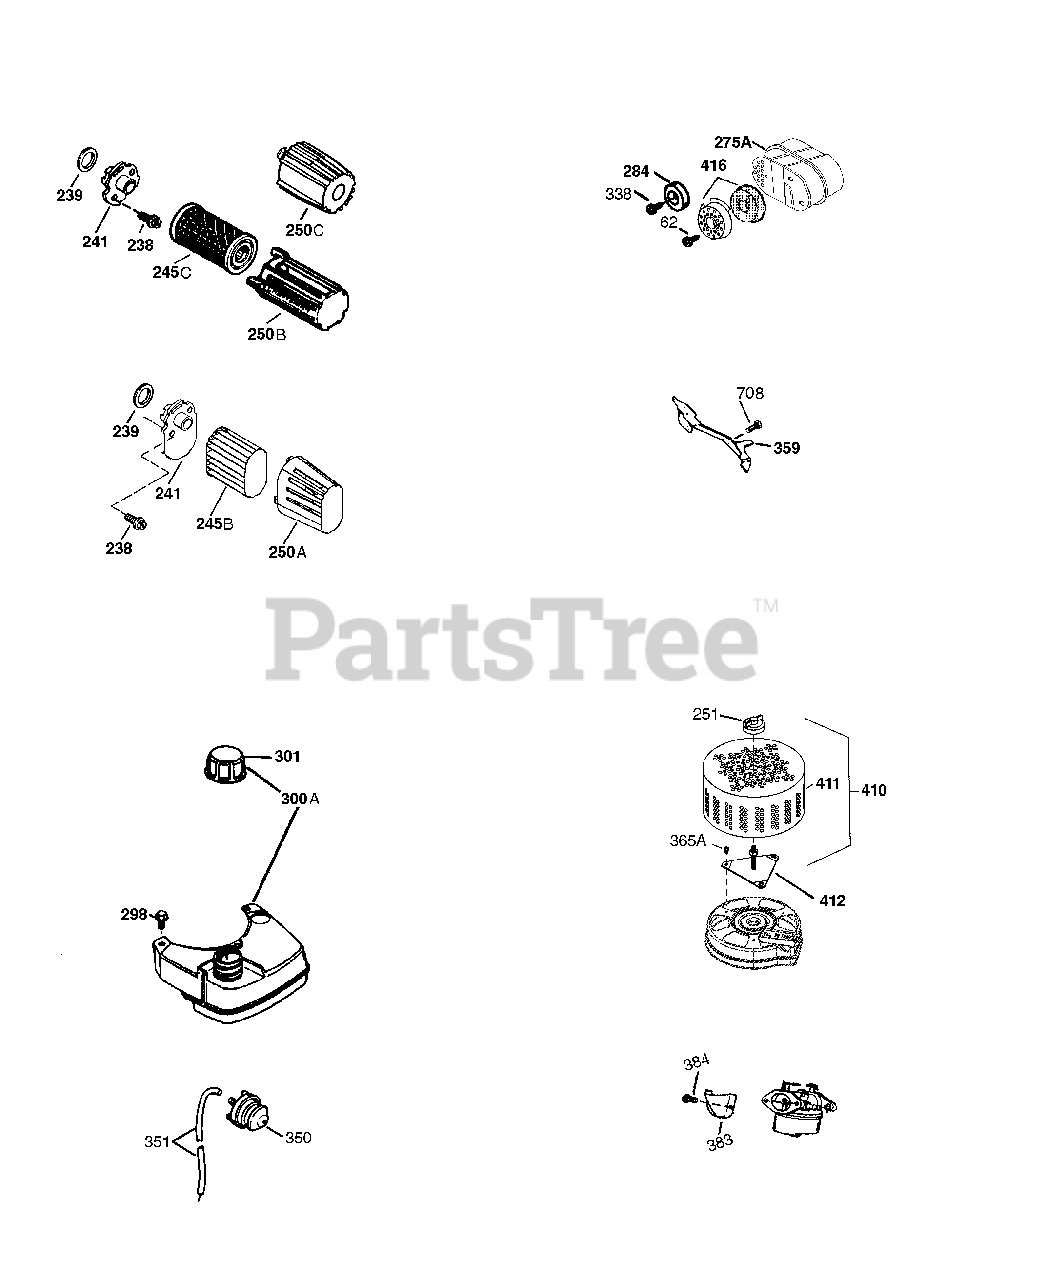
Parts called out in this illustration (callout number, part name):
239	* Carburetor to Baffle Gasket
275A	Spark Arrestor Muffler (Optional)(Inc l. 284,284A,416 & 417)
284	Muffler Deflector (Incl. 284A) Option al
301	Fuel Cap Gasket
301	Fuel Cap
338	Screw, 10-32 x 1/2" (Optional)
350	Primer Bulb
351	Primer Line (5.75")
383	Carburetor Baffle
384	Screw, T-25, 10-32 x 3/8")
416	Spark Arrestor Kit (Incl. 417) Option al
900	Replacement Engine NONE
900	Replacement Short Block 750857, order from 71-999
999	Winter Maintenance Kit incl. 5W30 Oil , Spark Plug, Key, & Ultra-Fresh
999	Winter Maintenance Kit (incl. 0W30 Sy nthetic Oil, Spark Plug, Key, & Ultra -Fresh)
